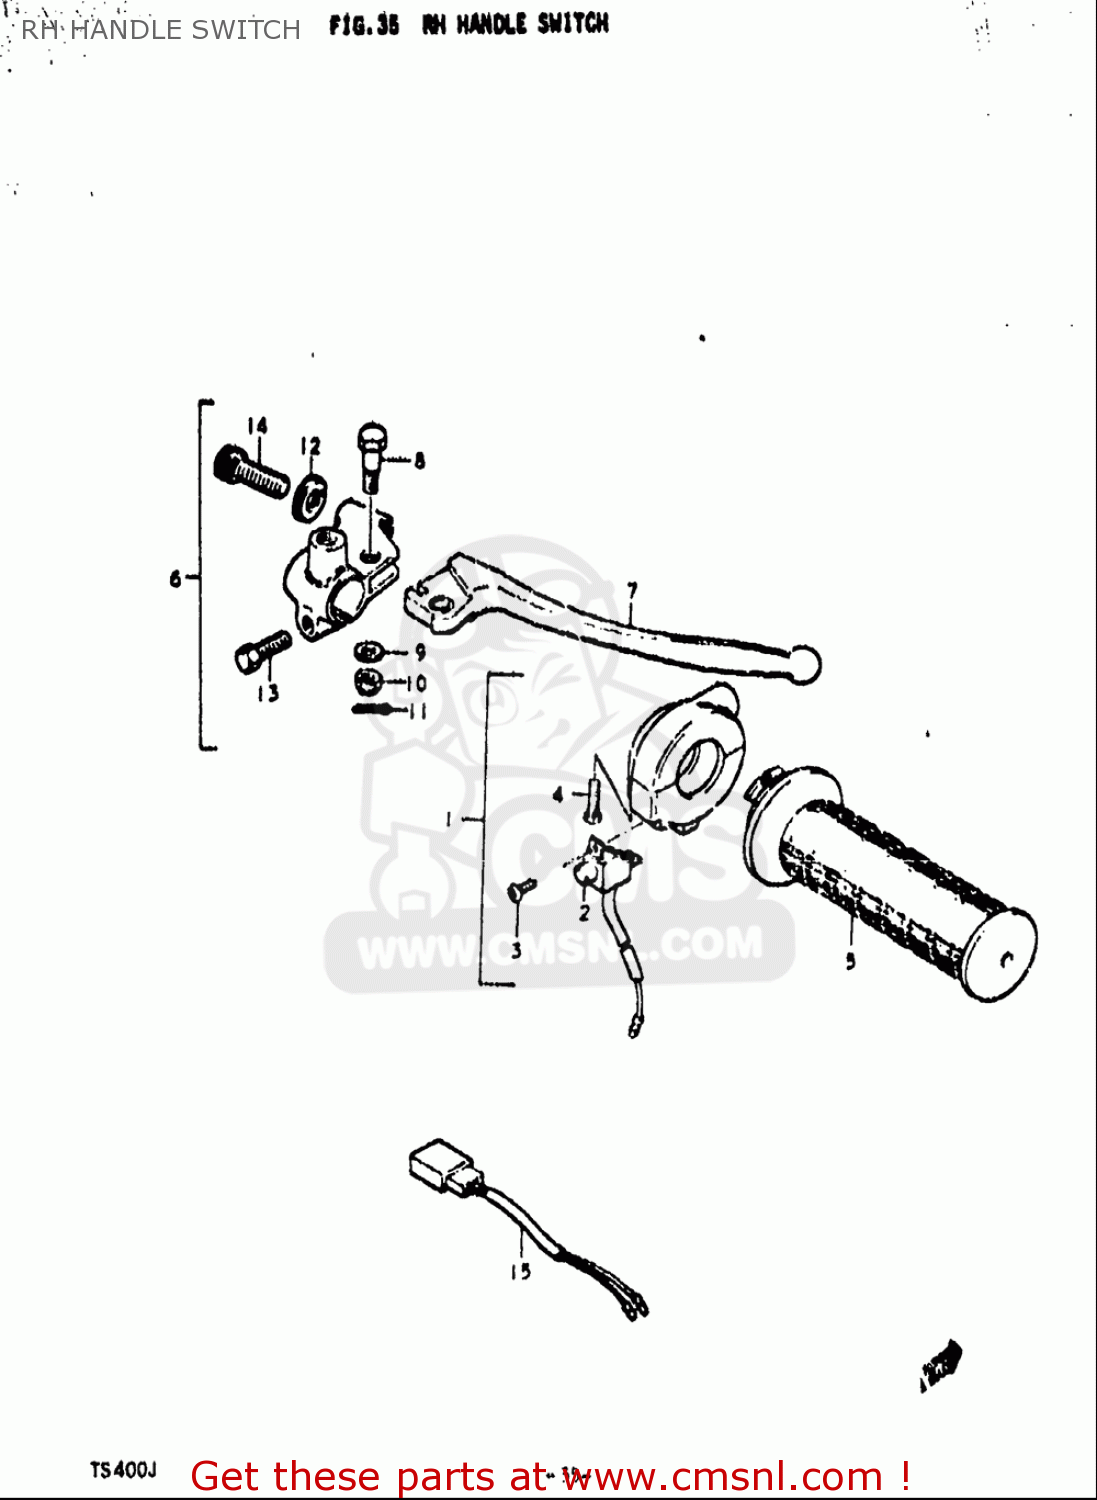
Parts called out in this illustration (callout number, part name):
3	SCREW
4	SCREW
5	GRIP,THROTTLE
6	BRAKE LEVER & SWITCH ASSY
7	LEVER,BRAKE
8	BOLT,LEVER PIVOT
9	WASHER,LOCK
10	NUT,LEVER FITTNG
11	PIN 16X20
12	NUT,CABLE ADJUSTER
13	BOLT
14	ADJUSTER,CABLE
15	LEAD WIRE
